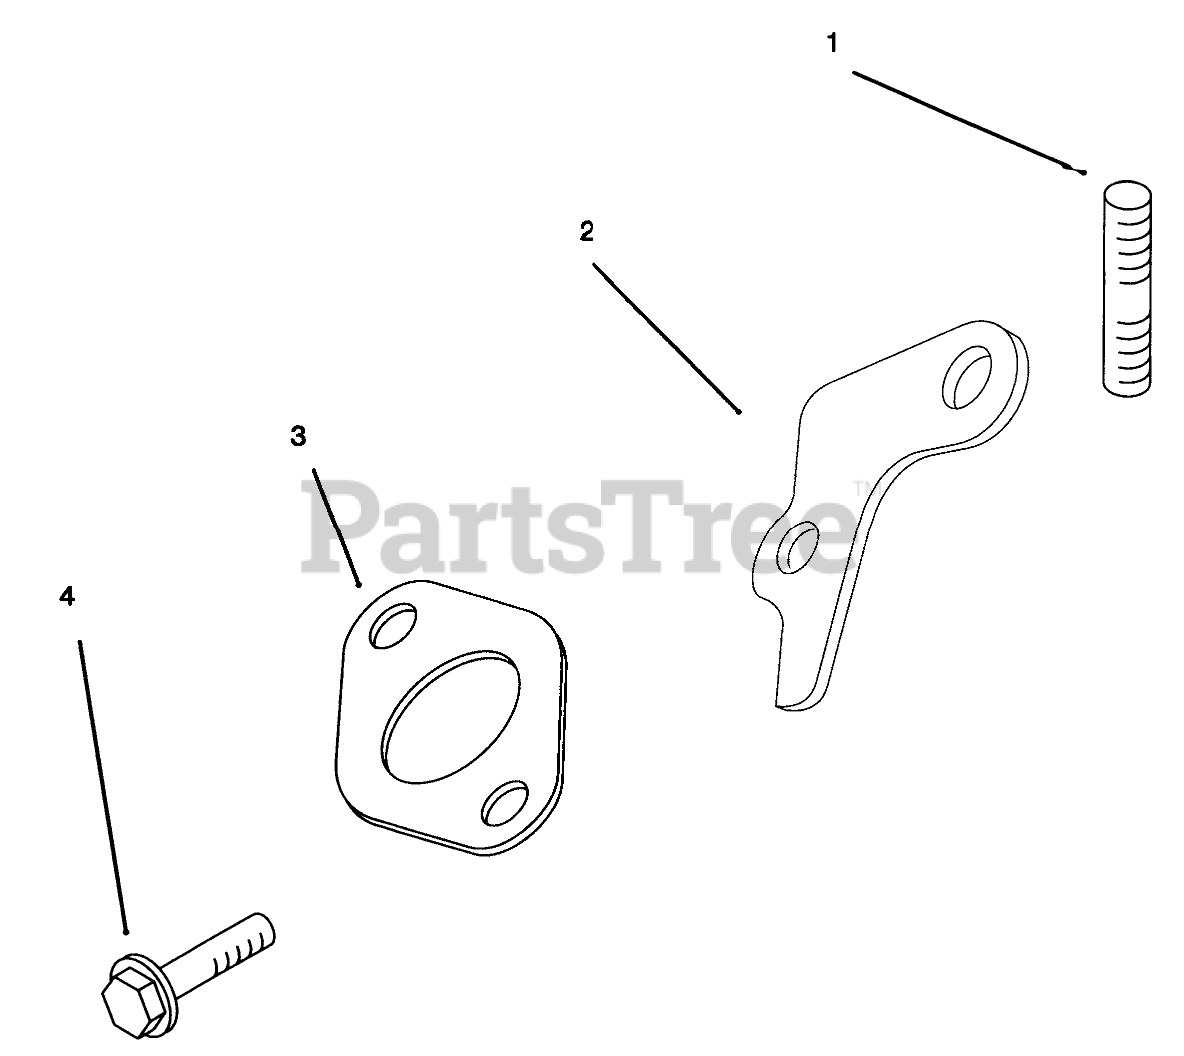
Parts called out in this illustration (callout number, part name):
1	Stud
2	Strap-Lifting
3	Gasket-Exhaust
4	Screw
